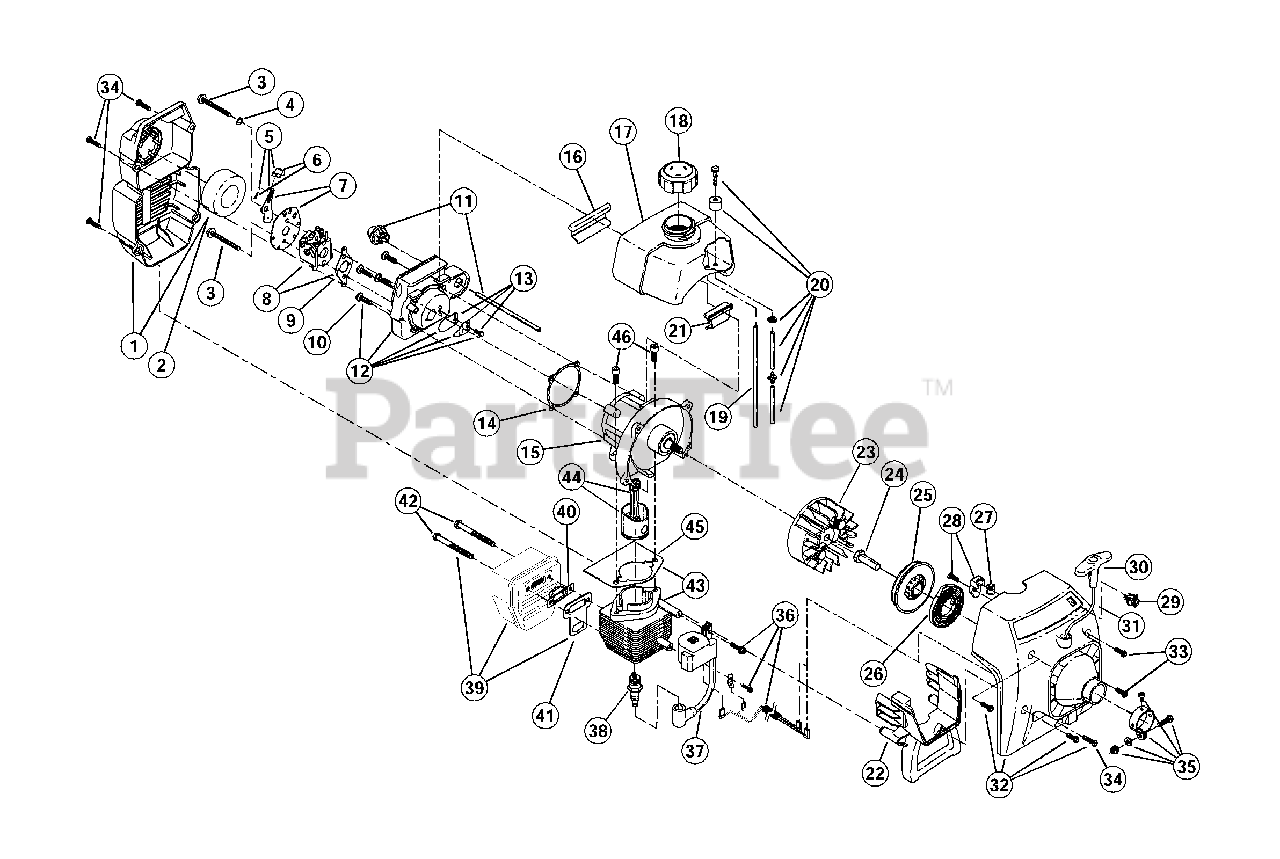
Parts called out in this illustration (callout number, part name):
1	Air Cleaner/Muffler Cover Assembly
2	Air Cleaner Filter
3	Carburetor Mounting Screw Assembly
4	Wavey Washer
5	Choke Lever Assembly
6	Choke Knob and Screw
7	Choke Lever and Plate
8	Carburetor Assembly
9	Carburetor Gasket
10	Carb Mount Screw
11	Primer and Hose Assembly
12	Carb Mount Assembly
13	Reed Assembly
14	Crank Case Gasket
15	Crank Case Service Assembly
16	Rear Mounting Pad
17	Fuel Tank Assembly
18	Fuel Cap Assembly
19	Fuel Return Line
20	Fuel Line Assembly
21	Front Mounting Pad
22	Shroud Extension and Stand
23	Flywheel Assembly
24	Square Nut Drive
25	Recoil Pulley Assembly
26	Recoil Spring
27	Rope Guide
28	Pulley Retainer Assembly
29	Switch Assembly
30	Pull Handle
32	Starter Housing Assembly
33	Housing Screw
34	Cover Screw
35	Upper Clamp Assembly
36	Wire Lead
37	Module Assembly
38	Spark Plug
39	Muffler Assembly
40	Spark Arrestor
41	Exhaust Gasket
42	Muffler Mounting Bolt
43	Cylinder Assembly
44	Piston and Rod Assembly
45	Cylinder Gasket
46	Cylinder Bolt
